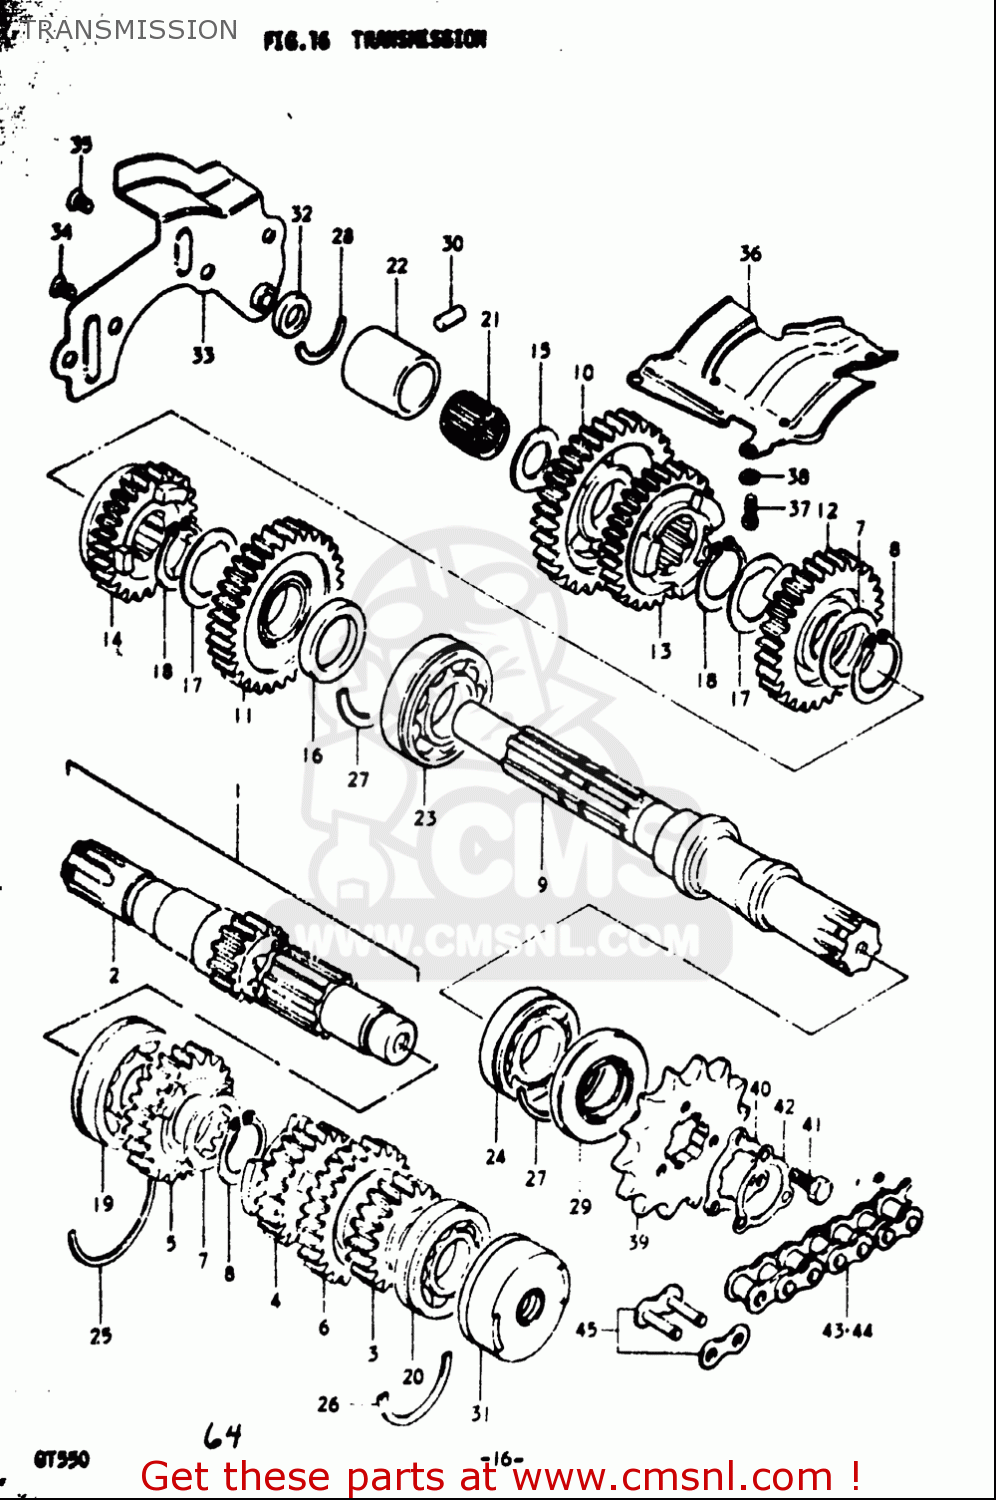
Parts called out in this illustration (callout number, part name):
7	WASHER,LOCK
8	CIRCLIP
15	WASHER (20X30X1)
17	WASHER,LOCK
18	CIRCLIP
20	BEARING(20X47X14)
22	BUSHING
23	BEARING
24	BEARING
25	C RING
26	C RING
27	C RING
28	C RING
30	PIN
32	SEAL,OIL(8X14X4)
34	SCREW
35	SCREW
37	SCREW
38	WASHER,LOCK
39	SPROCKET,ENGINE
40	PLATE,ENGINE SPROCKET
41	BOLT
42	WASHER
